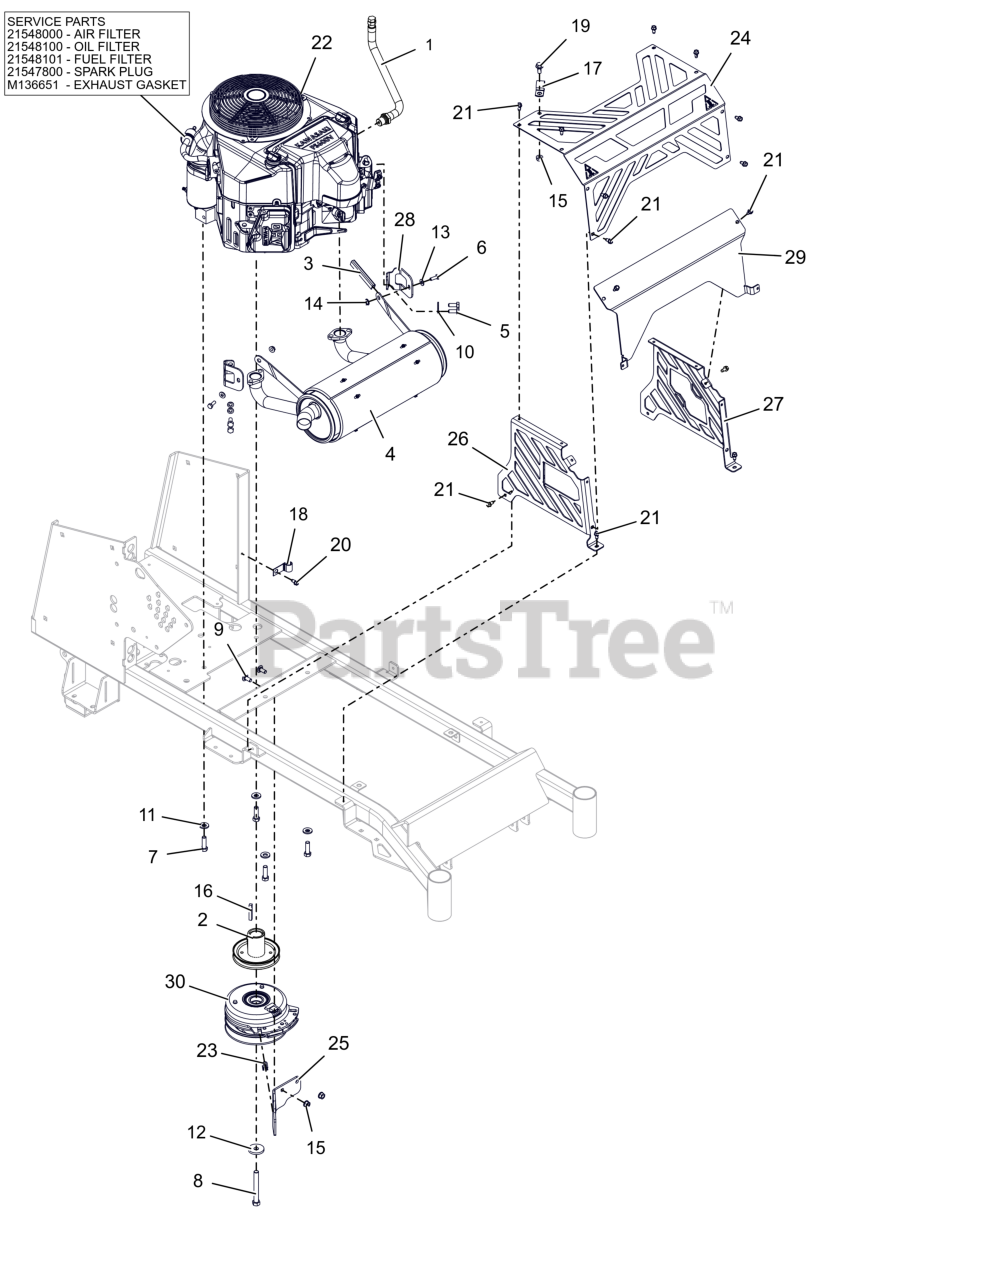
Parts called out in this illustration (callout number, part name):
1	HOSE, OIL DRAIN
2	SHEAVE, ENGINE 4.50 X 1.127
3	STRIP, COWL
4	EXHAUST, KAWASAKI FS
5	BLT, HEX M8-1.25X20 G8.8 ZCC
6	BLT, HEX .25-20X.75 G5 ZCC
7	BLT, HEX .38-16X1.25 G5 ZCC NT
8	BLT, HEX 0.4375-20X3.5 G8 ZCC NT
9	BLT, RHSSN.31-18X.750 G5 ZCC
10	WSHR,LK-REG .312X.078 ZCC
11	WASHER, 3/8" SPRING DISC
12	WASHER, 7/16" SPRING DISK
13	WSHR,FLT .281X.625X.065 ZCC
14	NUT-LK-CTR-FLG .25-20 ZC120
15	NUT,LK-CTR-FLG .31-18 GF ZCC
16	KEY-STR .25X1.75X.25
17	CLAMP, CUSHIONED STEEL .75
18	J-CLAMP
19	BLT- SERHFWH .312-18X.75 ZCC
20	SCR-TAP .25-20X.50 HWH ZCC
21	SCR-TAP .25X.50 HWH ZB500
22	ENGINE, KAWASAKI FS600V
22	AIR FILTER, KAWASAKI FR
22	OIL FILTER, KAWASAKI FR
22	FUEL FILTER-KAWASAKI FR
22	PLUG, SPARK
22	GASKET, MUFFLER #
23	BSHG, CLUTCH
24	PANEL- MFLR GUARD-FRONT
25	BRKT- CLUTCH STOP
26	PANEL, MFLR GUARD,RS (BLACK)
27	PANEL, MFLR GUARD,LS (BLACK)
28	BRKT- MUFFLER MOUNT
29	BAFFLE, MFLR GUARD (BLACK)
30	CLUTCH, WARNER 5219-287
